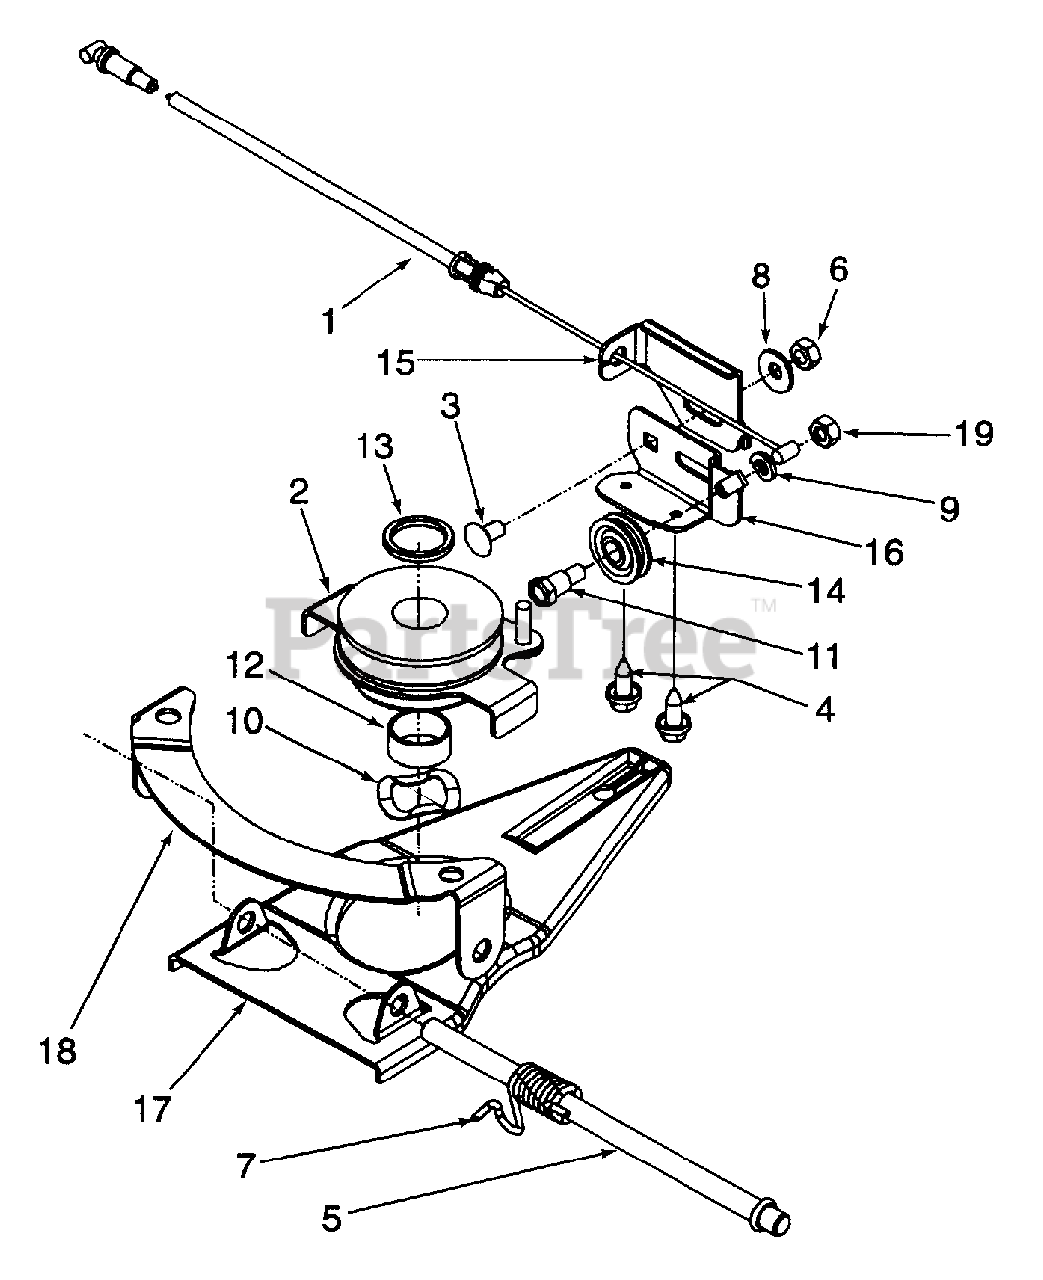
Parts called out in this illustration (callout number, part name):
1	6 Spd. Cable
2	Pulley Ass'y Multi Spd.
3	Scr. 1/4-20 x .50 Carr.
4	Scr. AB 1/4-14 x .625 Hex wash
5	Pivot Shaft
6	Nut 1/4-20
7	Torsion Spring LH
8	Bell Wash. .265 X .75 X .062
9	Lock Wash. 1/4 Reg Duty
10	Wave Wash. 1,38 x .88 x .029
11	Shld.Scr. .340 x .350 x 1 /4-20
12	Slev Spcr .88 ID x 1.00 OD x.48
13	Slev Spcr .88 ID x 1.13 ID x .12
14	Roller Cable
15	6 Spd: Cable Adj. Bracket
16	6 Spd. Cable Mt. Bracket
19	Hex Nut 1/4-28
